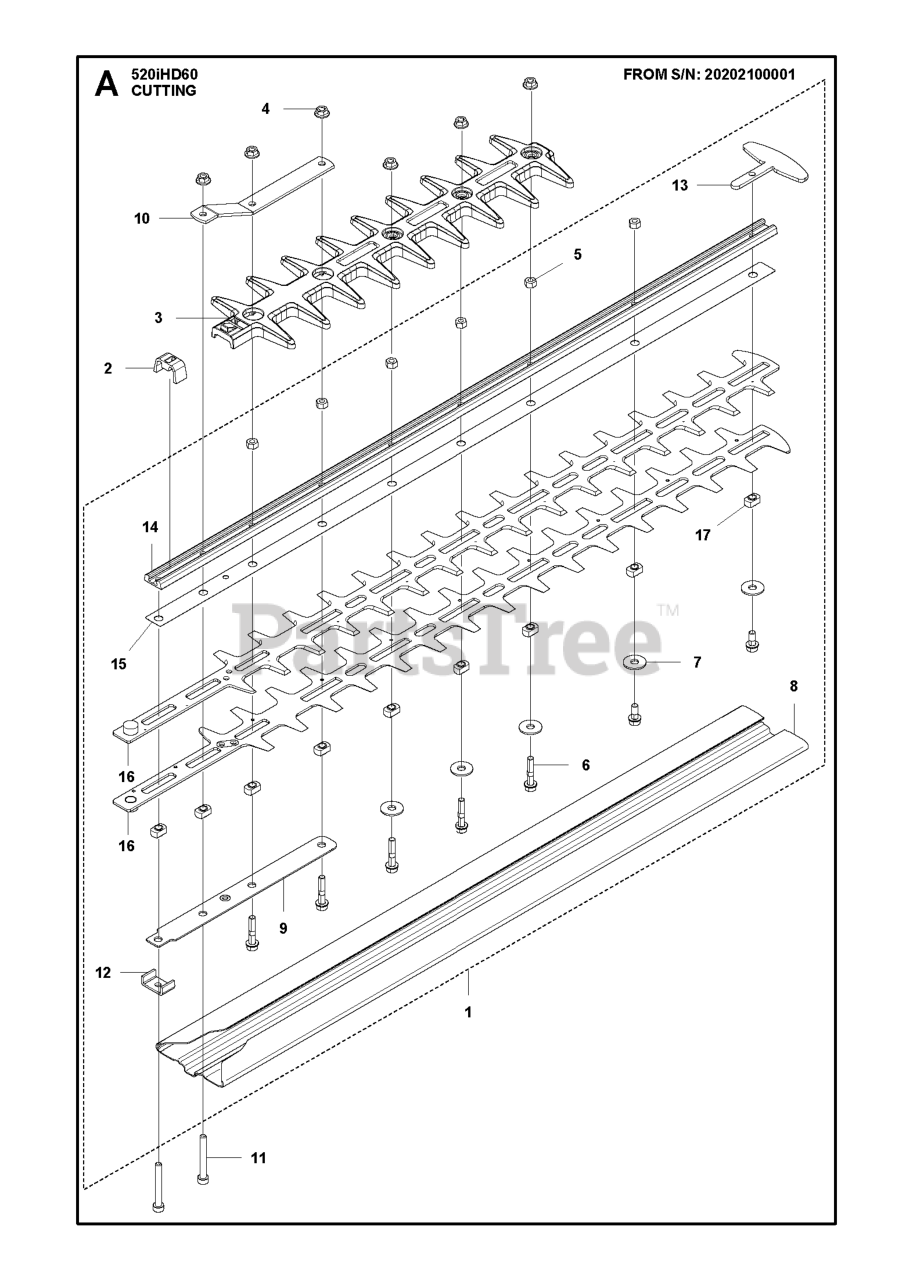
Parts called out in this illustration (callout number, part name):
1	CUTTING DECK
3	PROTECTION ASSY BLADE
4	HEXAGON NUT FLANGE M5 8 ZN/FE
6	SCREW M5X25 T27
7	WASHER 6,4X18X1,5
8	TRANSPORT GUARD CUTTING DECK L
10	SUPPORT CUTTING DECK
12	BRACKET CUTTING DECK
13	PROTECTION BLADE TIP
15	WEAR PLATE
16	BLADE ASSY HD60
17	SPACER CUTTING DECK
18	SCREW M5X16 T25
